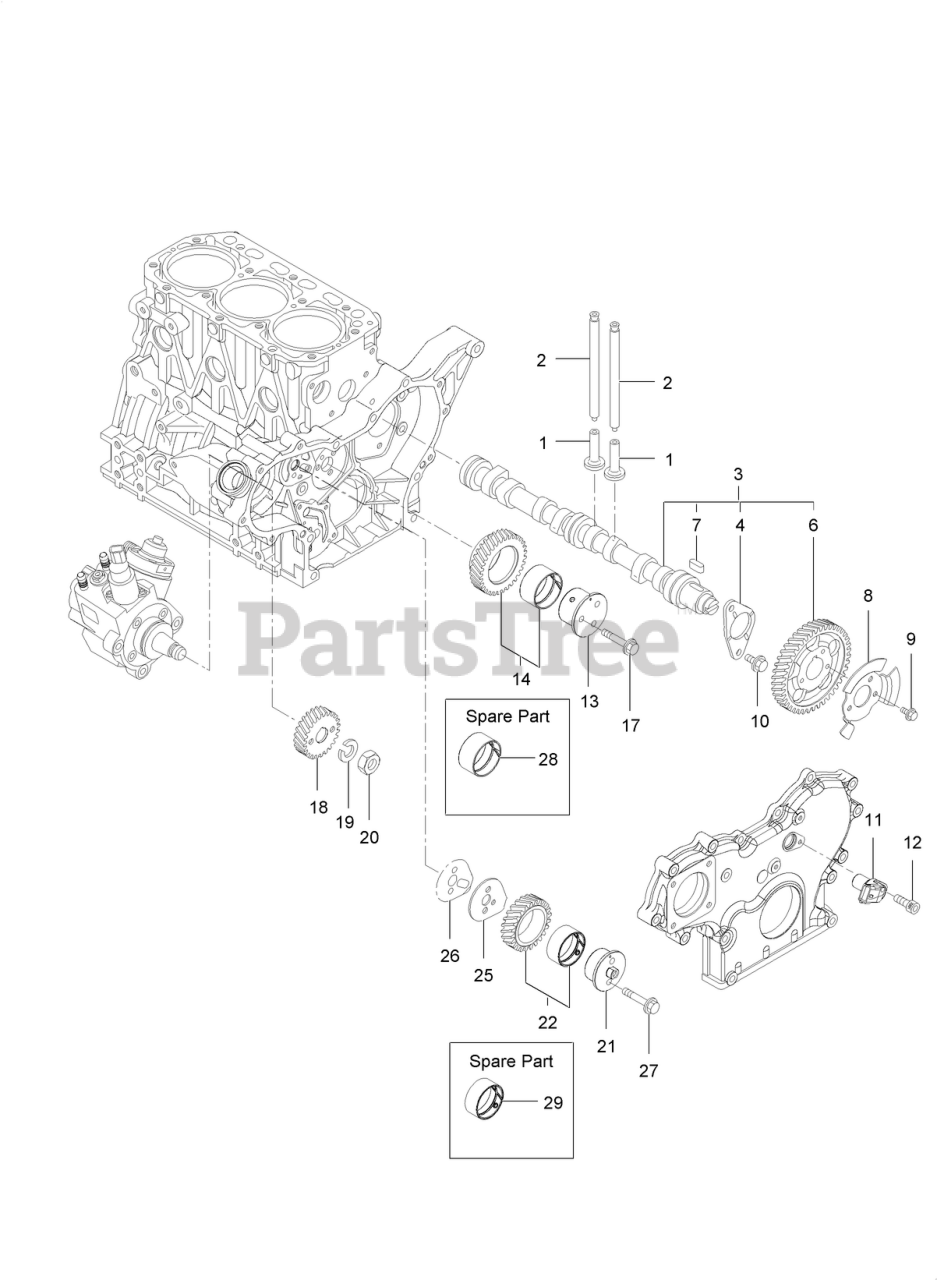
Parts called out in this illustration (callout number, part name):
2	ROD-PUSH
3	CAMSHAFT ASM
4	METAL-THRUST
6	Gear-Camshaft
8	PULSER, CAMSHAFT
11	SENSOR-REV, GEAR
13	Shaft-Idle, Gear A
14	IDLE GEAR A ASM
18	Gear-Pump, Supply
19	Washer-Spring
20	Nut-Lock
21	Shaft-Idle, Gear B
22	IDLE GEAR B ASM
25	Plate-Idle, Shaft
26	Gasket-Idle, Shaft B
28	BUSHING
29	BUSHING
